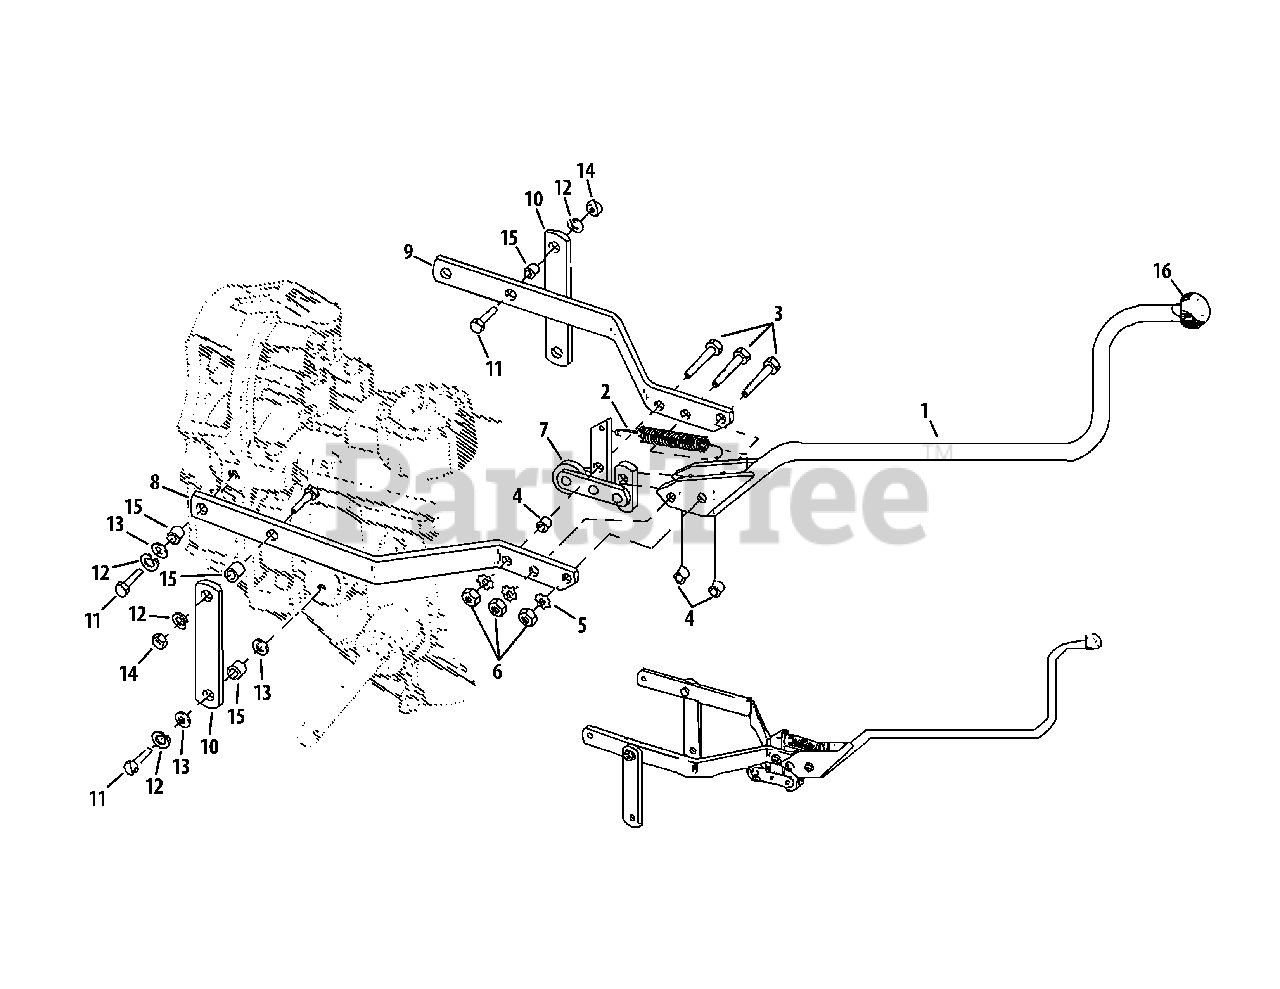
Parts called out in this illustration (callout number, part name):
1	Forward/Reverse Lever
2	Clutch Pawl Spring
3	Hex Bolt, 5/16"-18 x 1-1/2"
4	Bushing, .5 x .316 x .375
5	External Tooth Lockwasher, 5/16"
6	Hex Nut, 5/16"-18
7	Roller Assembly
8	Yoke (Left)
9	Yoke (Right)
10	Yoke Pivot Link
11	Hex Bolt, 3/8"-16 x 1"
12	Lockwasher, 3/8"
13	Flat Washer, 3/8"
14	Hex Nut, 3/8"-16
15	Bushing Spacer, .5 x .375 x .3
